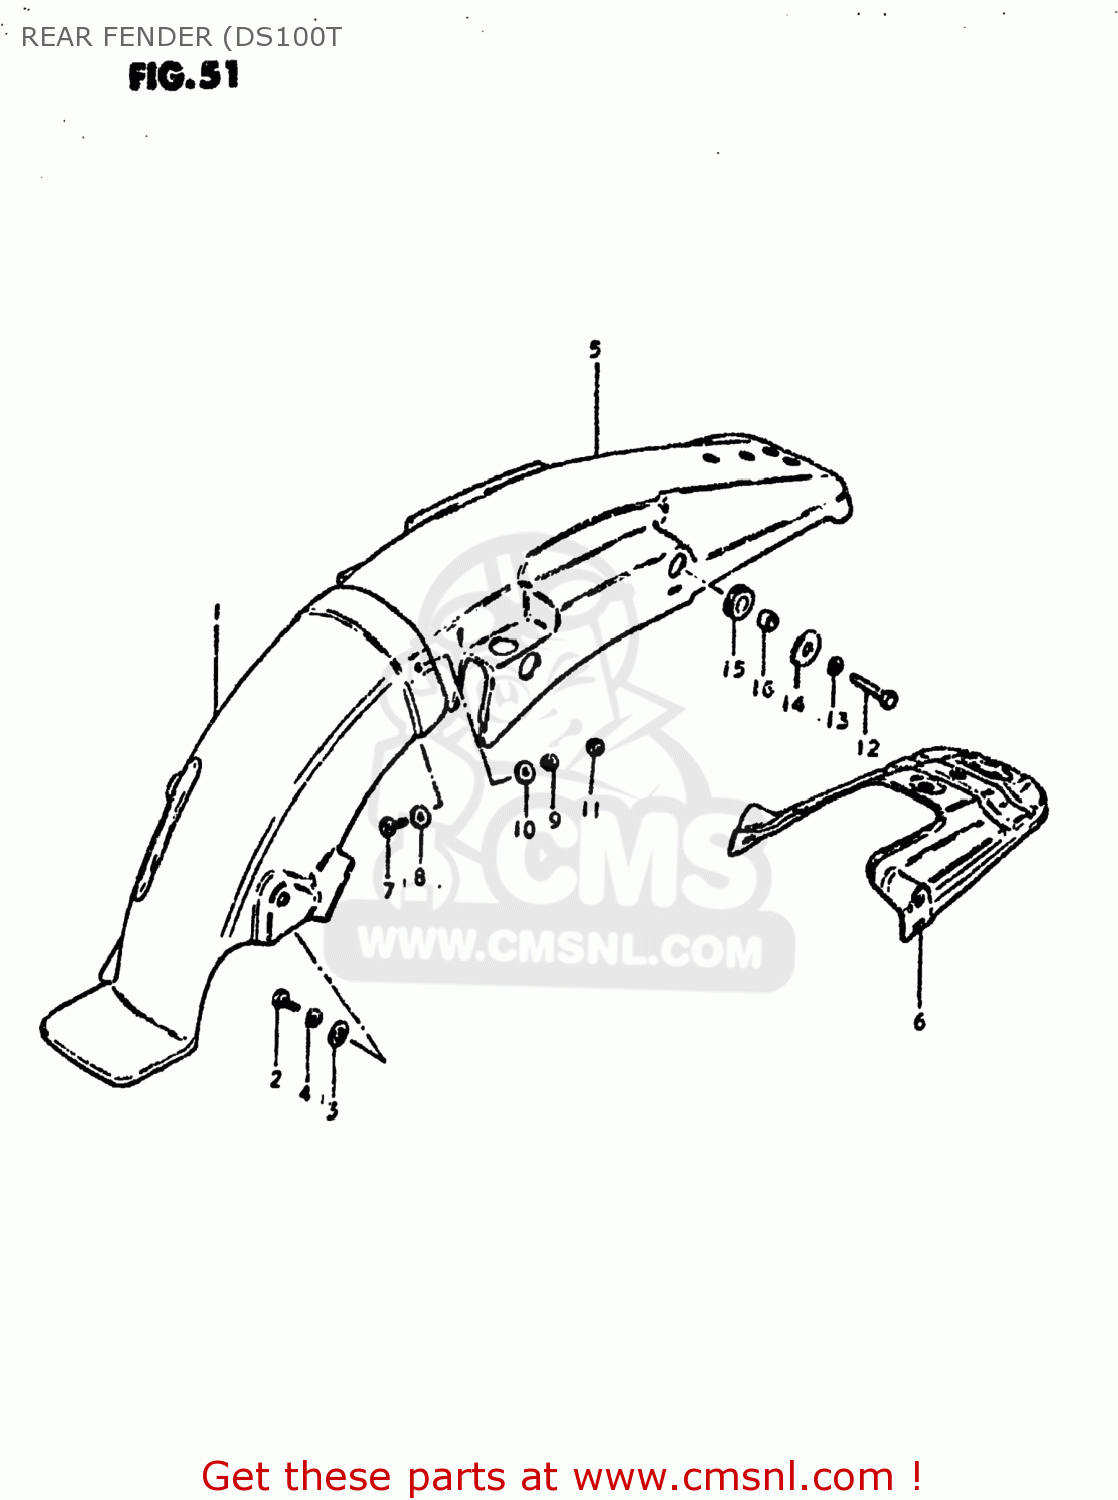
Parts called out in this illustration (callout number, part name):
1	BODY,REAR FENDER,FRONT
2	BOLT, UPPER
3	WASHER
4	LOCK WASHER
5	FENDER,REAR
6	REINFORCEMENT,RR FENDER
7	BOLT
8	WASHER (5.5X16X1.2)
9	LOCK WASHER
10	WASHER(5.2X16X1)
11	NUT
12	BOLT
13	LOCK WASHER
14	WASHER
15	CUSHION
16	SPACER (8.2X12X7.5)
